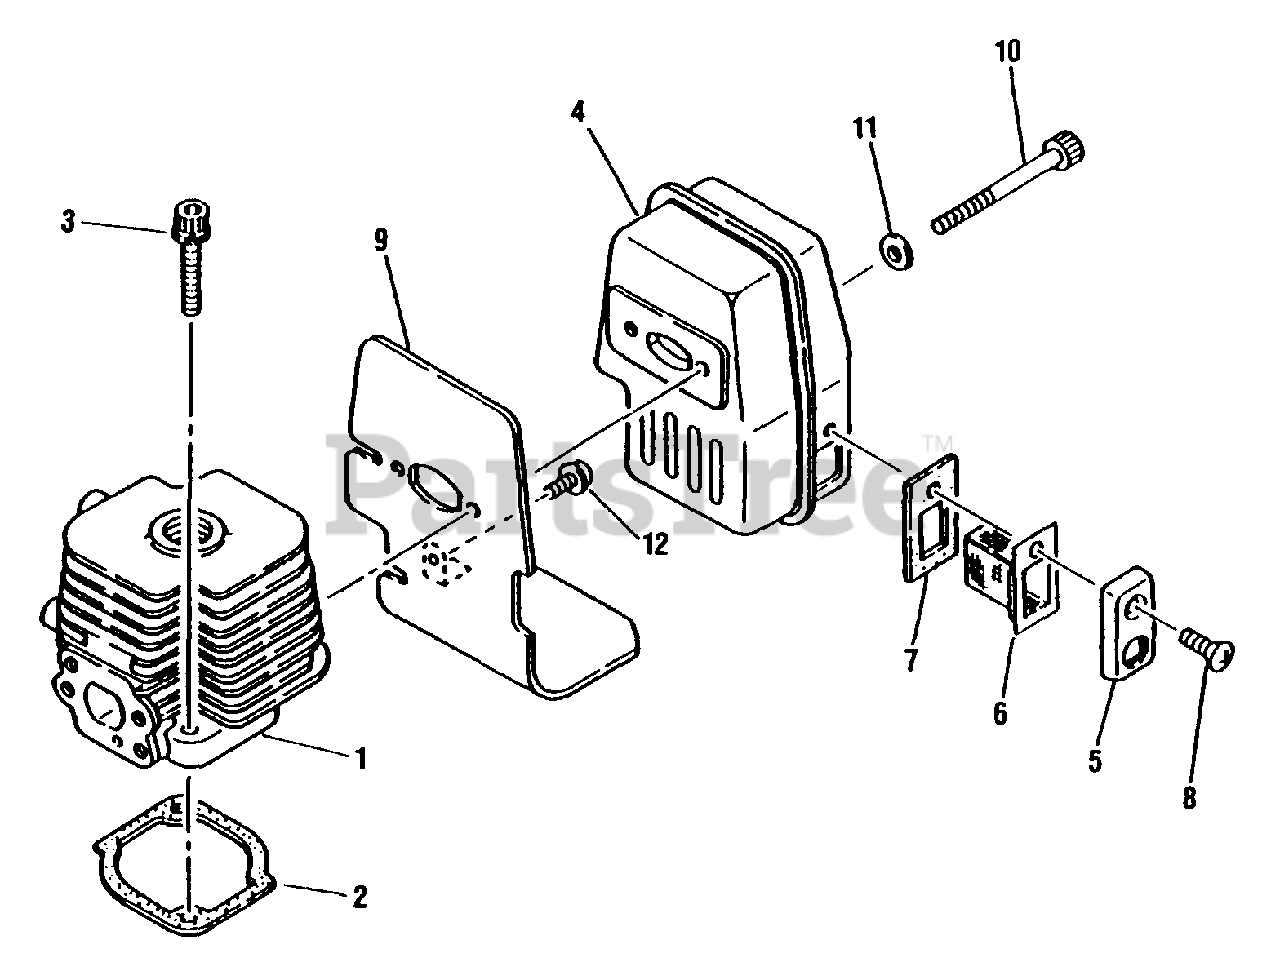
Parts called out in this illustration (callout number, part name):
1	CYLINDER
2	GASKET, CYLINDER
3	SCREW - 5X25
4	MUFFLER
5	CAP
6	SCREEN, SPARK ARRESTOR
7	GASKET, CAP
8	SCREW
9	SHIELD, EXHAUST
10	SCREW - 5X55
11	WASHER - 5
12	SCREW - 5X12
